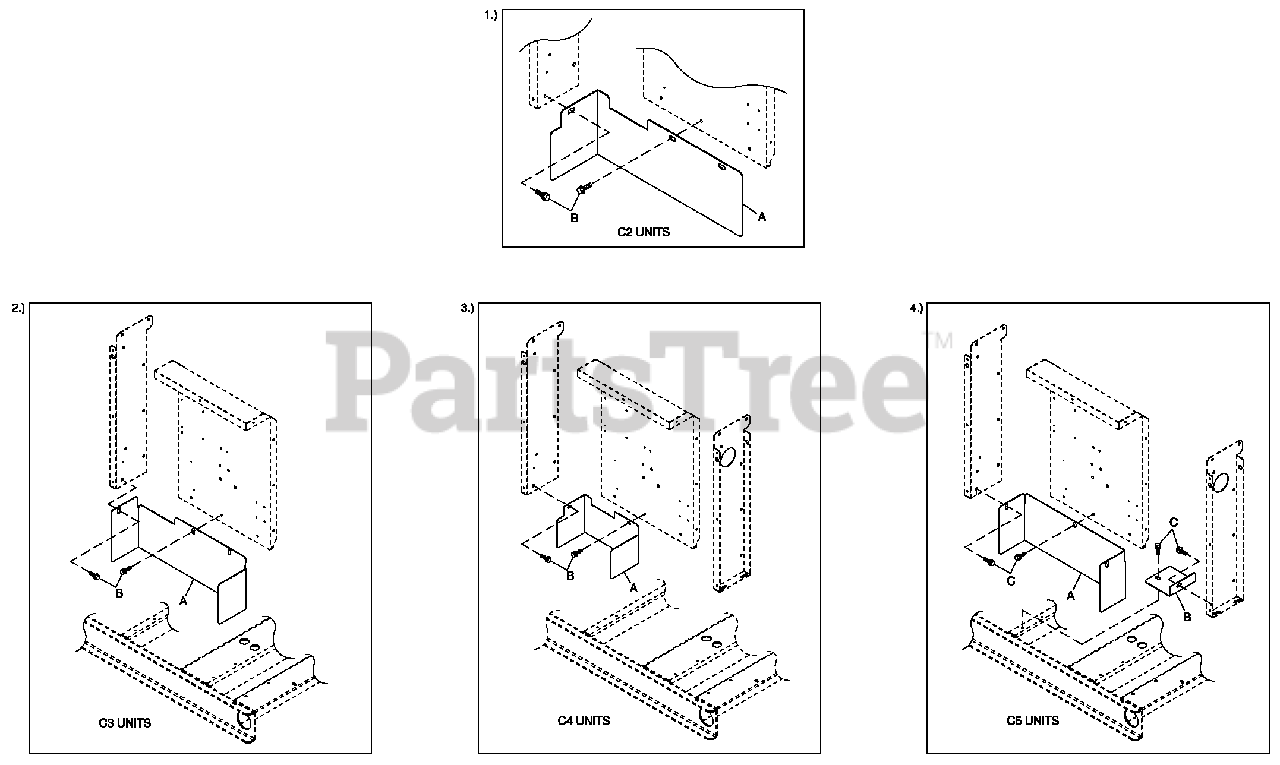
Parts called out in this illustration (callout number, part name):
1	C2 UNITS
2	C3 UNITS
3	C4 UNITS
4	C5 UNITS
A	SHIELD CONN BOX C2
B	SCREW THF M6-1 X 16 N WA Z/JS
A	SHIELD CONTROL STAND C3
A	SHIELD CONTROL STAND C4
A	SHIELD CONTROL STAND C5
B	SHIELD CONTROL STAND C5
C	SCREW THF M6-1 X 16 N WA Z/JS
